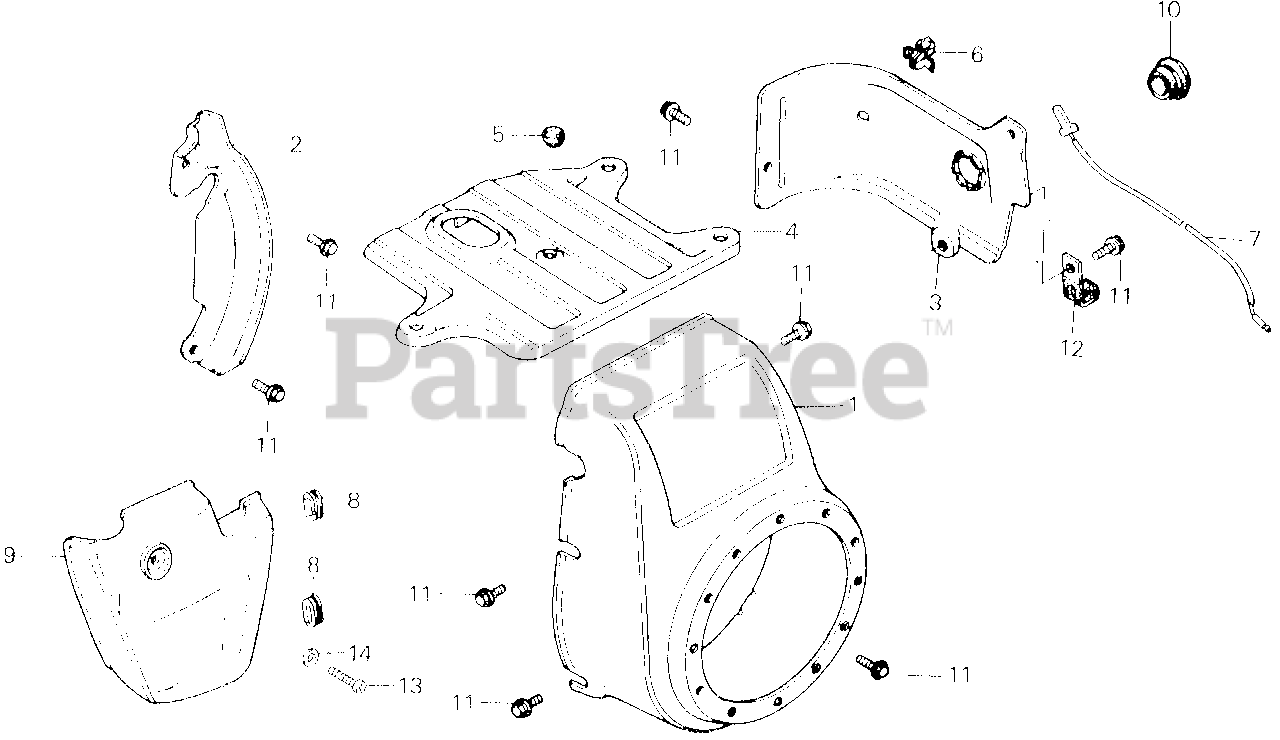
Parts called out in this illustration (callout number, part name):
1	COVER, FAN *R280* (POWER RED)
2	PLATE, SIDE
4	COVER, TOP
5	GROMMET, TOP COVER
6	CLIP, IGNITION WIRE (8MM)
7	WIRE A, ENGINE STOP
8	RUBBER, CHAIN CASE MOUNTING
9	COVER, ENGINE SIDE *R8* (BRIGHT RED)
10	GROMMET, DRAIN HOLE
11	BOLT, FLANGE (6X12) (CT200)
12	CLIP, WIRE
13	SCREW, PAN (6X20)
14	WASHER, PLAIN (6MM)
